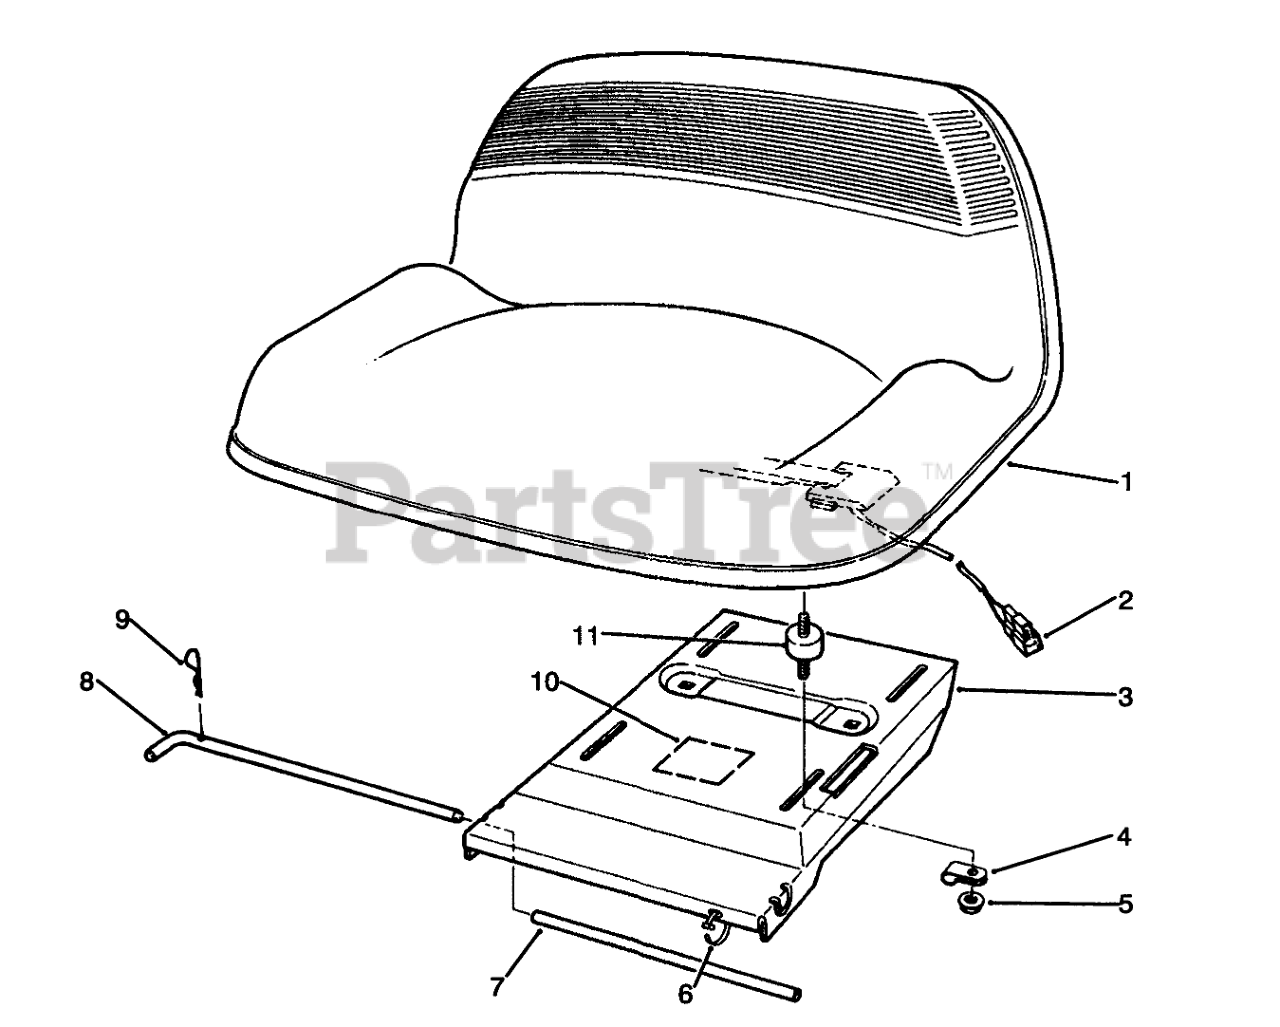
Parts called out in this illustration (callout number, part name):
1	SEAT
2	SWITCH-SEAT
3	Base-Seat
4	CLAMP
5	NUT-HF
6	TIE-CABLE
7	TUBE-SEAT
8	ROD-SEAT BASE
9	PIN-COTTER
10	DECAL-EUROPE
11	ISOLATER-SEAT
